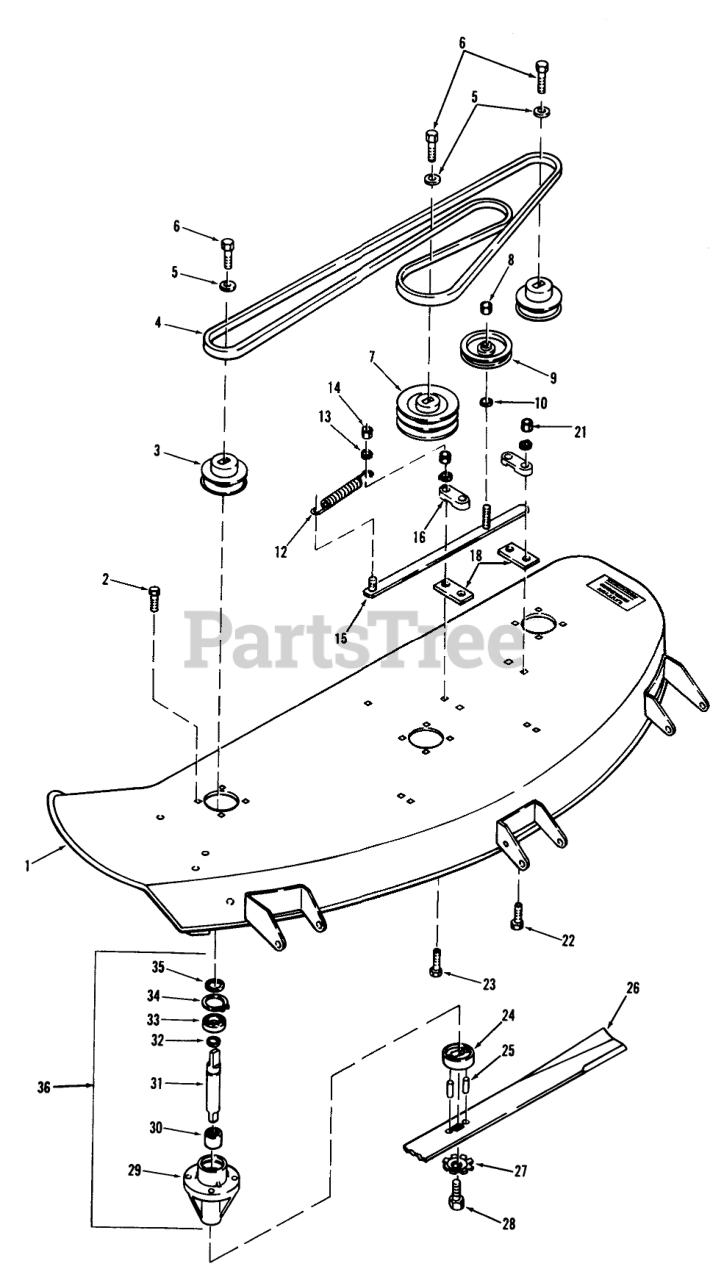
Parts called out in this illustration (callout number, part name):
1	Deck
1	Deck-42"
2	Bolt
3	Pulley-Right & Left
3	End Pulley
4	V-BELT
4	V BELT
5	WASHER
6	Bolt
7	Pulley-Center
7	Center Pulley
8	Nut
9	Idler Pulley
9	Pulley-Idler
10	Washer
12	SPRING R
13	WASHER 5/16 SAE
14	Nut
15	ASSY BAR IDLER SUPPO
16	Side Block
18	SLIDE
21	Nut
22	Bolt-Carriage
23	Bolt-Carriage
24	Cup-Spindle
25	SPIROL ROLL PIN
26	BLADE KIT 48 LF
26	BLADE KIT 42 LF
27	WASHER
28	Bolt
29	HOUSING SPINDLE
30	NEEDLE BEARING
31	SHAFT SPINDLE
32	Snap Ring
33	BEARING
34	INT SNAP RING
35	WASHER-THRUST
36	Spindle Assy.
